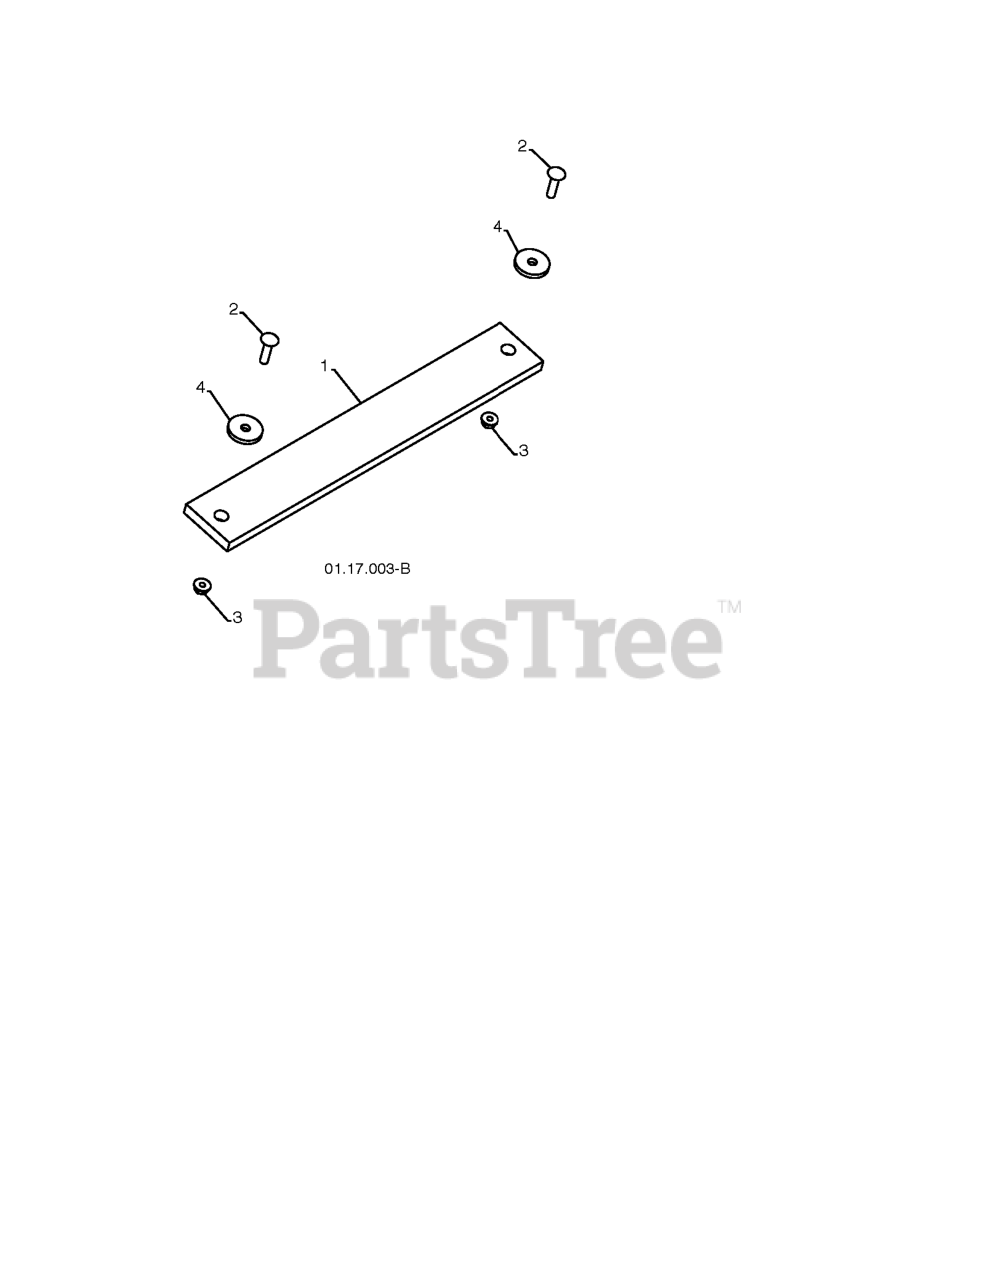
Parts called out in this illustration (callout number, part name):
1	WEIGHT AUGER HOUSING 30
2	BOLT.CARRIAGE.5/16-18
3	NUT.LOCK.5/16-18
4	WASHER.FLAT.34X1.38X22
